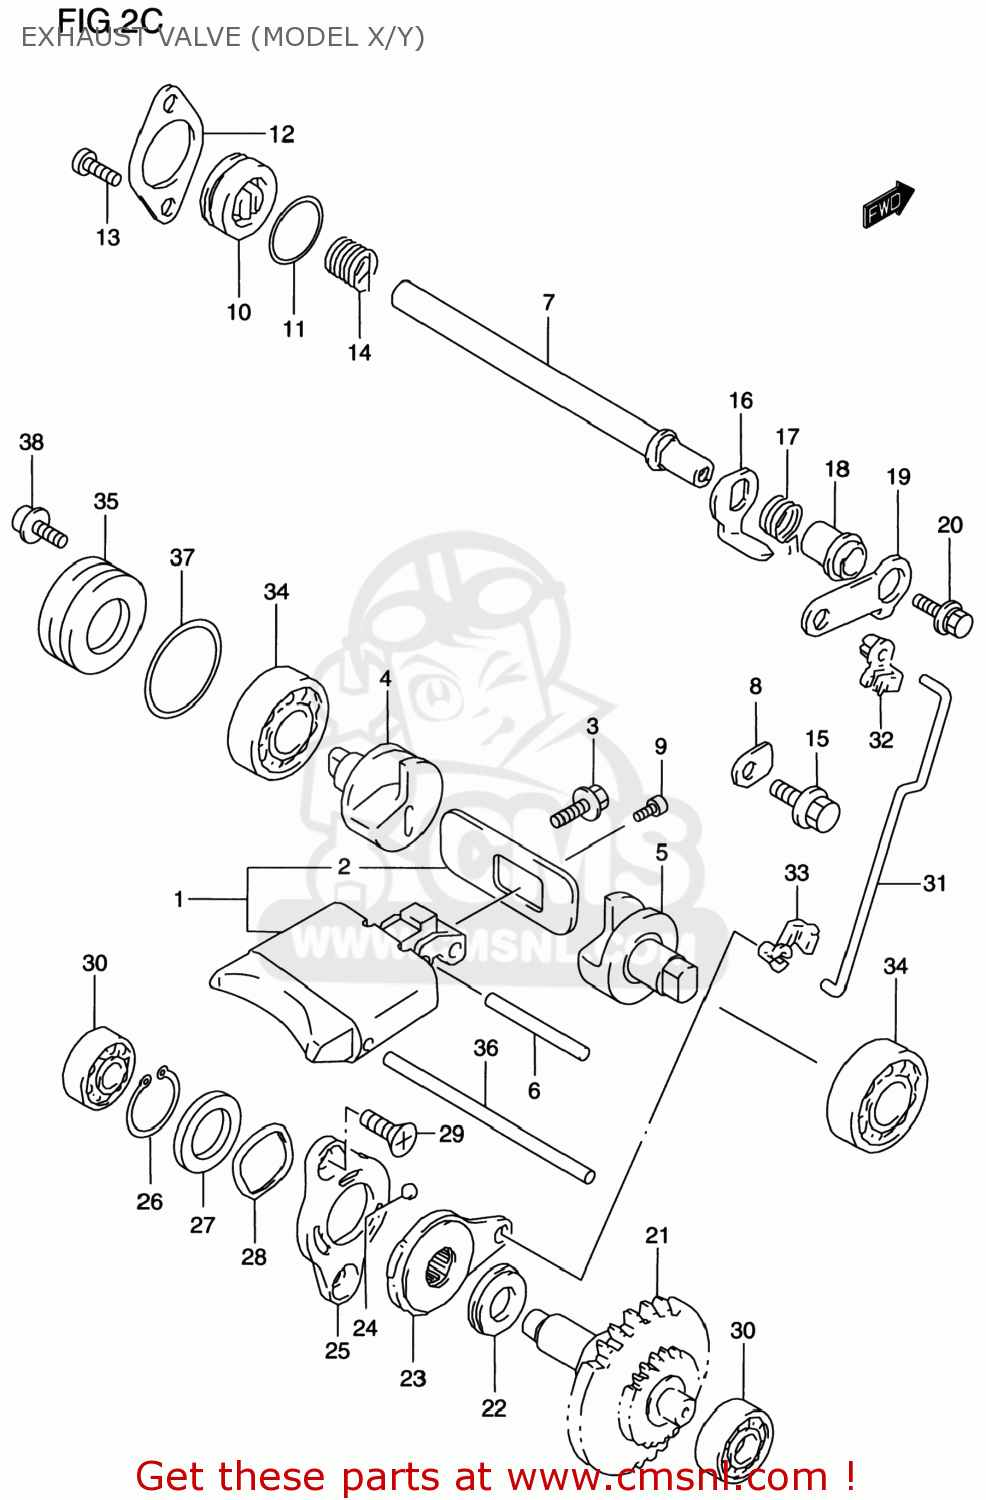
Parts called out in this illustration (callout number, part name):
1	VALVE ASSY,EXHAUST MAIN
2	GUIDE,EXHAUST MAIN VALVE
3	SCREW 5X12
4	VALVE,EXHAUST SIDE,RIGHT
5	VALVE,EXHAUST SIDE,LEFT
6	PIN(4X20)
7	SHAFT,EXHAUST VALVE
8	RETAINER
9	BOLT(4X8)
10	CAP,EXHAUST VALVE
11	O RING(D:1.9,ID:22.6)
12	RETAINER,EXHAUST VALVE
13	BOLT
14	SPRING,EXHAUST VALVE
15	BOLT
16	LEVER,EXHAUST VALVE NO.2
17	SPRING
18	SPACER,EXHAUST VALVE
19	LEVER,EXHAUST VALVE NO.1
20	BOLT(5X12)
21	GOVERNOR ASSY,EXHAUST VALVE
22	BEARING(10X22X2.8)
23	ACTUATOR,EXHAUST VALVE
24	BALL
25	STARTER,EXHAUST VALVE ACTUATOR
26	CIRCLIP
27	SHIM(19.1X25X0.3)
28	WASHER
29	SCREW(5X10)
30	BEARING(8X22X7)
31	ROD,EXHAUST VALVE
32	BUSH,EXHAUST VALVE ROD NO.1
33	BUSH,EXHAUST VALVE ROD NO.2
34	BEARING
35	CAP,EXHAUST SIDE VALVE
36	PIN
37	O RING(D:3.1,ID:26.4)
38	SCREW 5X12
